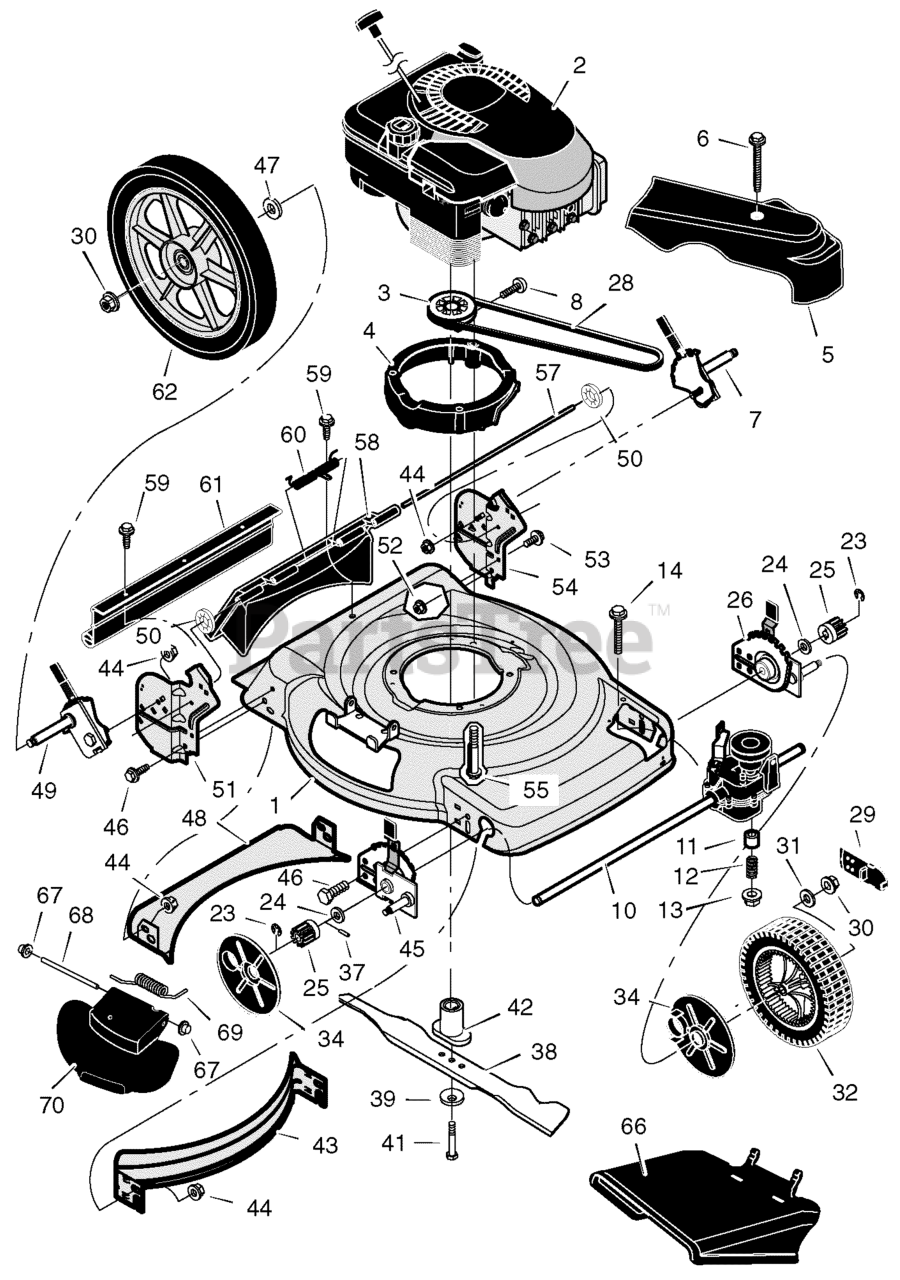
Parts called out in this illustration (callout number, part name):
1	Housing
2	Engine*
3	Pulley, Drive
4	Spacer, Engine
5	Cover, Belt (Black)
7	Adjuster, Left Rear Height
10	Transmission *
11	Spacer
12	Spring, Compression
13	Nut
14	Bolt
23	E-Ring
24	Washer
25	Gear, Pinion
26	Adjuster, Left Front Height
29	Cap, Hub
30	Nut, Flange
31	Washer
32	Wheel & Tire, Front
34	Cover, Dust
37	Pin, Drive
39	Washer, Belleville
42	Adapter, Blade
43	Baffle, Front
44	Nut, Flange
45	Adjuster, Right Front Height
46	Bolt
47	Washer
48	Baffle, Rear
49	Adjuster, Right Rear Height
50	Retainer, Push
51	Bracket, Right Handle
52	Nut, Flange
53	Bolt
54	Bracket, Left Handle
55	Bolt, Engine
57	Rod, Pivot
58	Door, Rear (Black)
60	Spring
61	Guard, Rear
62	Wheel & Tire, Rear
66	Deflector, Chute (Black)
67	Push On Cap
68	Rod, Pivot
69	Spring, Torsion
70	Cover, Mulch (Black)
